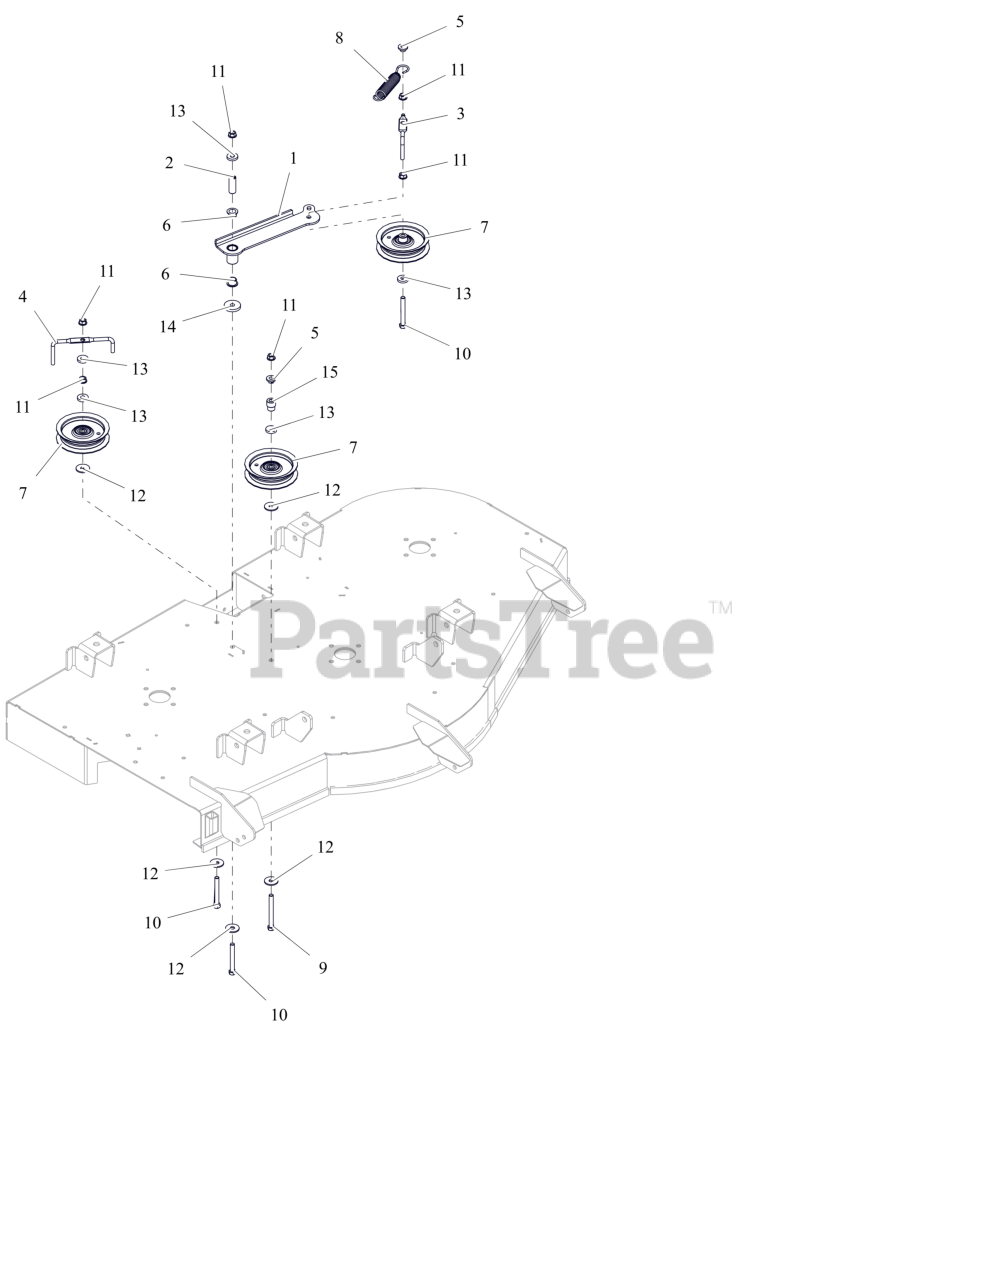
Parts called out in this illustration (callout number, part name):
1	WLDMT- IDLER ARM - 52"
2	SPACER, .375IDX.625ODX1.66 PM
3	WIREFORM, BELT FINGER
4	BELT FINGER
5	BSHG-FLG .385X.500X.875X.406
6	BSHG-FLG, .625X.750X.500X1.00
7	IDLER, FLAT - 4.06" X .75"
8	SG-TENS .135X.98X6.0 WLD 62
9	BLT, HEX .38-16X3.50 G5 ZCC
10	BLT, HEX .38-16X3.00F G5 ZCC
11	NUT-LK-CTR-FLG .375-16 GF ZCC
12	WSHR FL STL .406X1.25X.10ZC120
13	WSHR, FLT .406X1.00X.188 ZCC
14	WSHR, FLT .406X1.50X.245 ZCC
15	BUSHING, IDLER (P/M)
